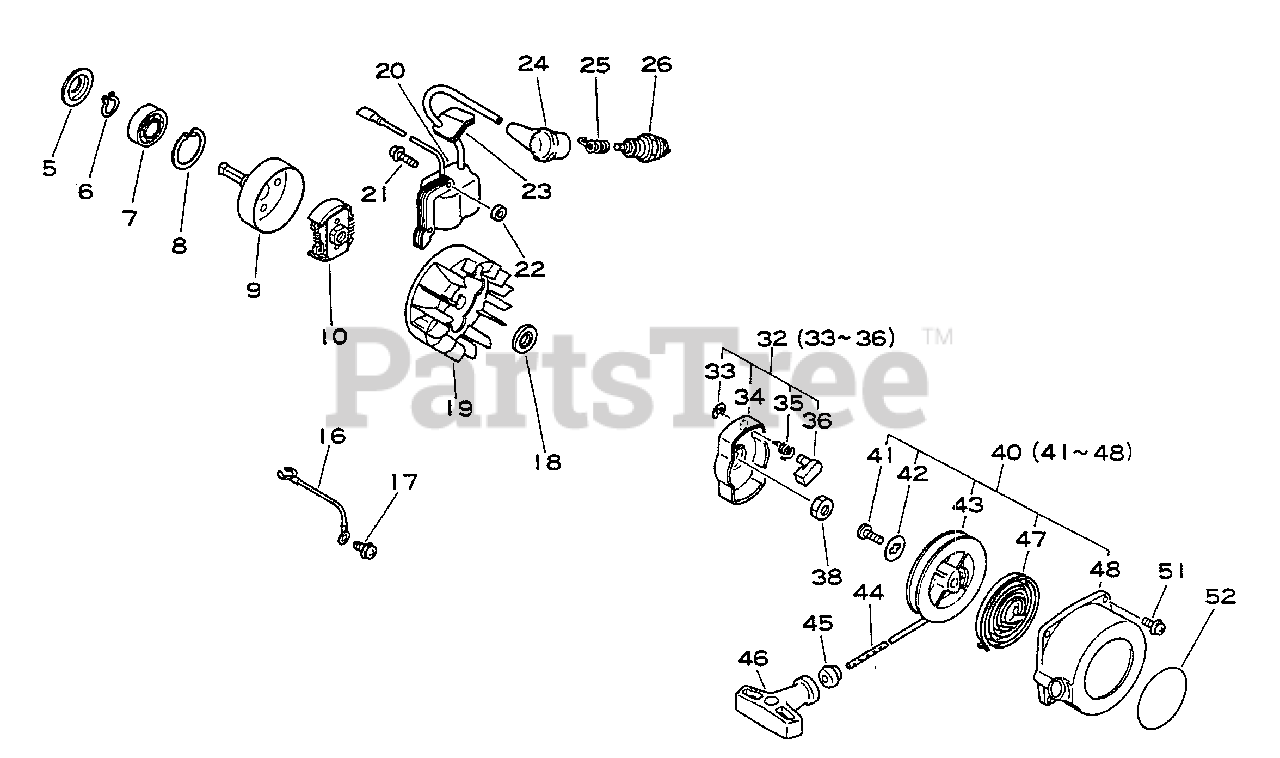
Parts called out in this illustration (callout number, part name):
5	STOPPER, PIPE
6	RING, RETAINING - 12
7	BEARING, BALL 6201
8	RING, SNAP Ø32
9	DRUM, CLUTCH
10	CLUTCH ASSY
16	LEAD - GROUND
17	SCREW 5×10
18	WASHER
19	FLYWHEEL
20	COIL, IGNITION
21	SCREW 4×22
24	CAP, SPARK PLUG
25	TERMINAL, SPARK PLUG
26	SPARK PLUG - CJ-7Y
32	STARTER PAWL ASSY
33	RING, RETAINING - 6
34	CATCHER, PAWL
35	SPRING, RETURN
36	PAWL, STARTER
38	NUT 8×1.25
40	STARTER ASSY
42	WASHER
43	REEL, ROPE
44	ROPE, STARTER
45	GUIDE, ROPE
46	GRIP, STARTER
47	SPRING, RECOIL
48	CASE, RECOIL STARTER
51	SCREW 4×16
52	LABEL, ECHO
